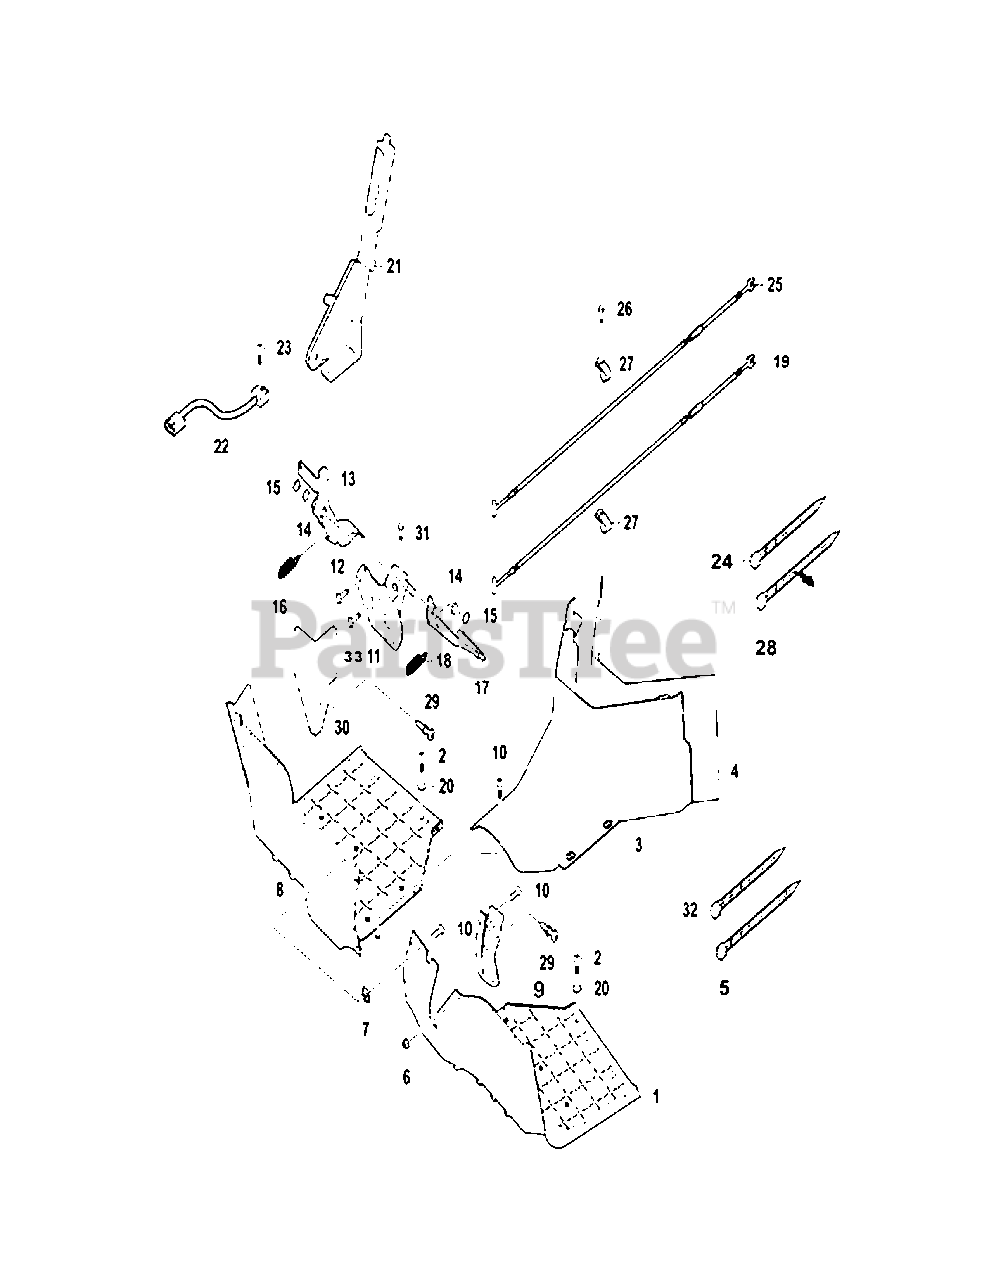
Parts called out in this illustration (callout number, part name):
1	Left Footrest Protector
2	Cross small plate head screw M5×16
3	Axle Cover
4	Insulation Paper III
5	Zip Tie L=300
6	Hexagon Flange Self-Lock Nuts M6
7	Nut Clip M6
8	Right Footrest Protector
9	Dustproof Plate, Brake Pedal
10	Cross large plate head screw M6×16
11	Rear Brake Pump Bracket Assy
12	Hexagon Flange Bolt M8×16
13	Accelerator Pedal Welding Assy
14	Washer15×22×1.5
15	Washer 12×1
16	Tension Spring VI
17	Welding Joint, Parking Pedal
18	Tension Spring VII
19	Throttle Cable
20	Washer 5×10×1.0
21	Parking System
22	Parking Sensor
23	Screw M4×12
24	Zip Tie-L=300
25	Parking Brake Cable
26	Hexagon Flange Bolt M6×16
27	Clip For Cable
29	Expansion Bolt(Plastic)
30	Mudguard For Brake Pump
31	Hexagon Flange Bolt M8×20
32	Zip Tie-L=370
33	Hexagon Flange Bolt M8X25
